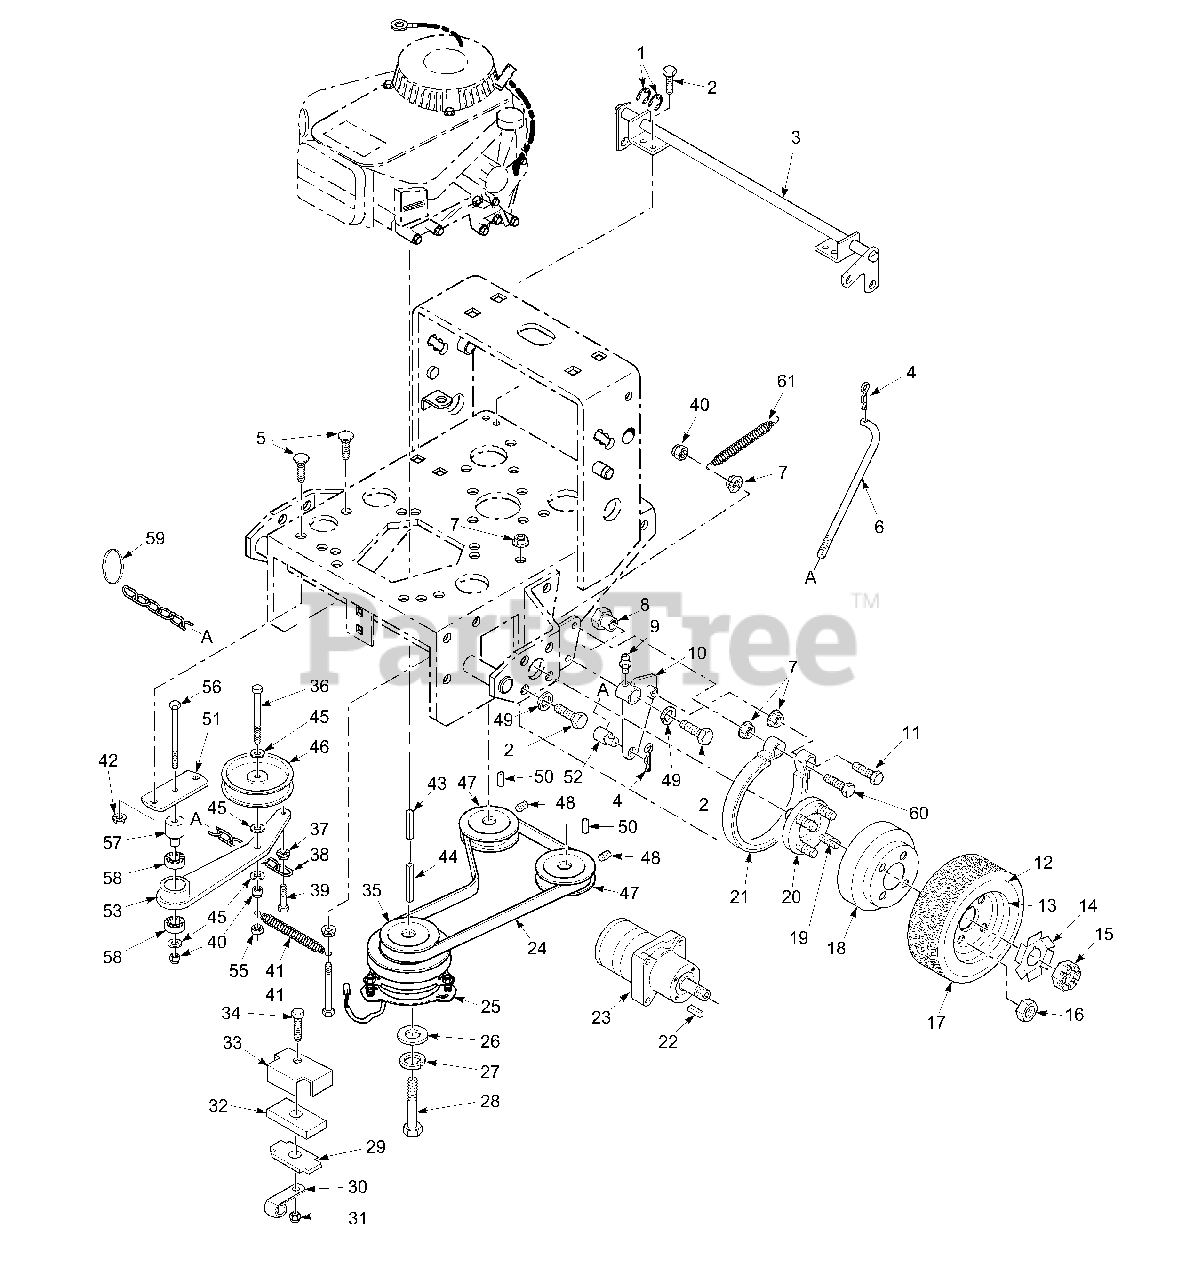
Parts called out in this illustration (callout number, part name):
1	Retaining Ring, 3/4" Ext. "E"
2	Bolt, Hex Head 3/8-16 x 1"
3	Brake Shaft Assembly Weldment
4	Hair Pin, Cotter (.094 x 1.62)
5	Bolt, Carriage 5/16-18 x .75"
6	Brake Rod, Lower
7	Nut, Hex Serrated Flange 3/8-16
8	Bushing, Brake
9	Grease Fitting
10	Brake Actuator Weldment, LH
11	Bolt, Hex Head 3/8-16 x 2.25"
12	Tire, 18 x 8.50-8, 4 Ply
13	Rim Assembly
14	Lockwasher, Wheel Motor
15	Nut, Hex Castle 3/4-28
16	Nut, Lug
17	Wheel Assembly
18	Brake Drum
19	1/2-20 Serrated Bolt
20	Hub,Wheel
21	Brake Band, 7.5"
22	Key, Woodruff 3/16 x .75"
23	Wheel Motor
24	Belt, Pump Drive
25	Electric Clutch
26	Flatwasher, 7/16" (.469 x 1.75 x .25)
27	Lockwasher, 7/16" Spring
28	Bolt, Hex Head M10-1.5 x 65mm
29	Plate, Backing
30	Clamp, Wire Loom
31	Nut, Hex Elastic Stop 5/16-18
32	Rubber Pad, Clutch Stop
33	Retainer, Clutch Stop
34	Bolt, Hex Head 5/16-18 x 1.75"
35	Pulley,Pump Drive-Engine
36	Bolt, Hex Head 3/8-16 x 2.75"
37	Nut, Hex Serrated Flange 1/4-20
38	Chain
39	Bolt, Hex Head 1/4-20 x 1.25"
40	Nut, Hex Elastic Stop 3/8-16
41	Spring, Pump Belt Idler
42	Nut, Hex Serrated Flange 5/16-18
43	Key, 1/4 x 1/4 x 2.75"
44	Key, 1/4 x 1/4 x 1"
45	Flatwasher, 3/8" (.391 x .938 x .105)
46	Pulley, Idler 4.5"
47	Pulley, Pump Shaft
48	Setscrew, 5/16-18 x 3/8"
49	Lockwasher, 3/8" Spring
50	Key, 5mm x 5mm x 25mm
51	Base, Idler Pivot
52	Swivel Joint
53	Idler Arm Weldment, Pump
55	Locknut, 3/8-16 Center Lock
56	Bolt, Hex Head 3/8-16 x 3"
57	Pivot, Idler (Long)
58	Ball Bearings
59	Ring, Split
60	Bolt, Hex Head 3/8-16 x 2.63"
61	Spring, Return
